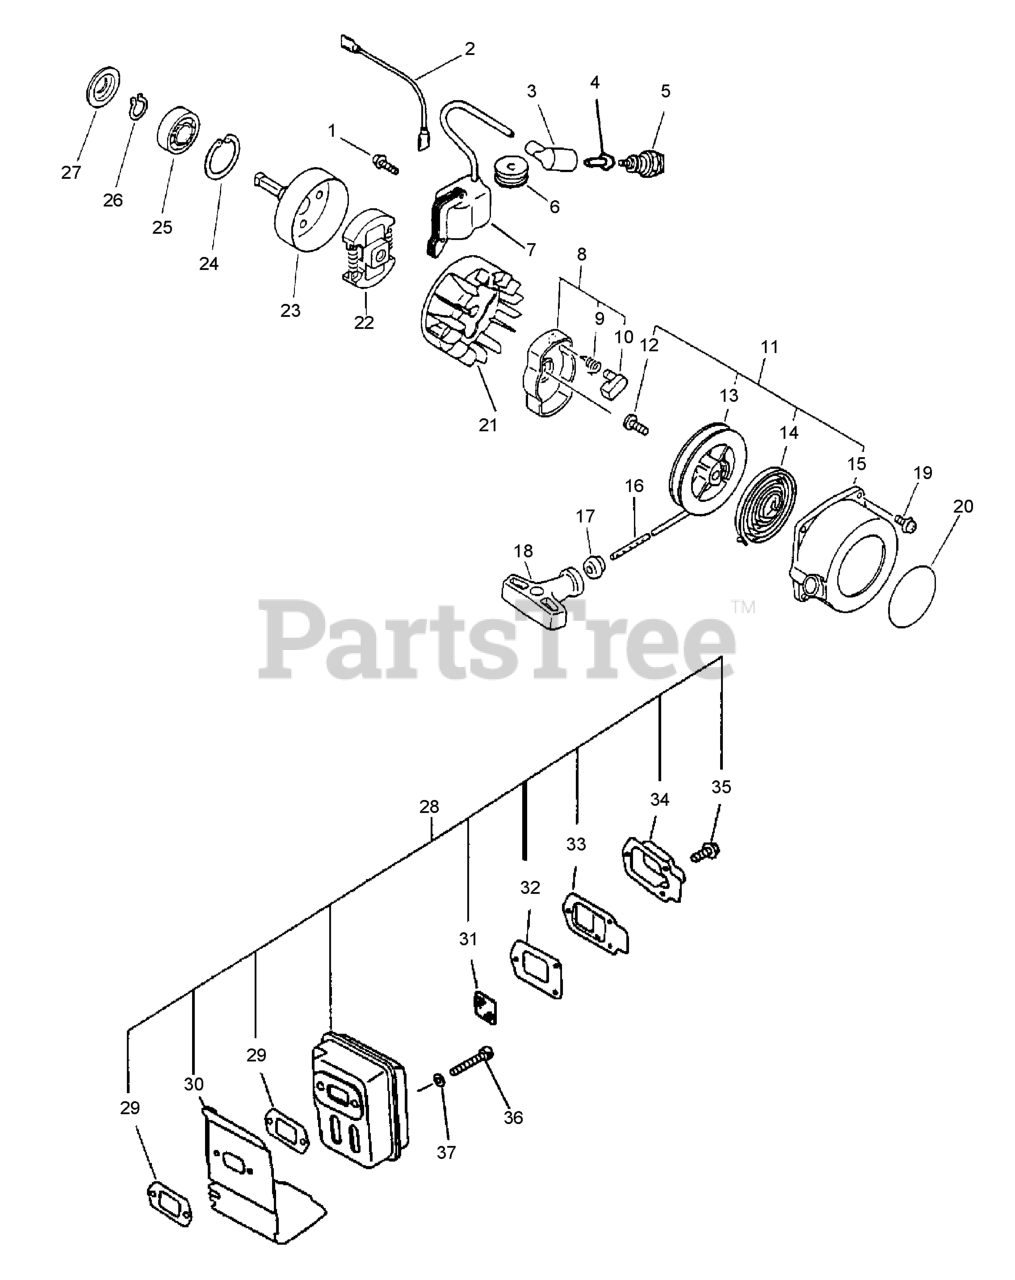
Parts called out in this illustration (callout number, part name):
1	SCREW 4x22
2	LEAD
3	CAP, SPARK PLUG
4	TERMINAL, SPARK PLUG
5	SPARK PLUG - BPM-7Y
5	SPARK PLUG - BPMR7A
6	GROMMET
7	COIL, IGNITION
8	PAWL ASSY, STARTER
9	SPRING, RETURN
10	PAWL, STARTER - BLACK
11	STARTER ASSY, RECOIL
13	REEL, ROPE
14	SPRING, RECOIL
15	CASE, RECOIL STARTER
17	GUIDE, ROPE
18	GRIP, STARTER
19	BOLT 4x16
20	LABEL - ECHO
21	FLYWHEEL
22	CLUTCH ASSY
23	DRUM, CLUTCH
24	RING, SNAP 32
25	BEARING, BALL 6201-ZZ
26	RING, SNAP 12
27	STOPPER
28	MUFFLER ASSY
29	GASKET, EXHAUST
30	COVER, EXHAUST
31	SCREEN, SPARK ARRESTER
32	GASKET, EXHAUST
33	GUIDE, EXHAUST
34	OUTLET, EXHAUST
35	SCREW 4x10
36	BOLT 5x55
37	WASHER, FLAT 5.5x10x0.8
